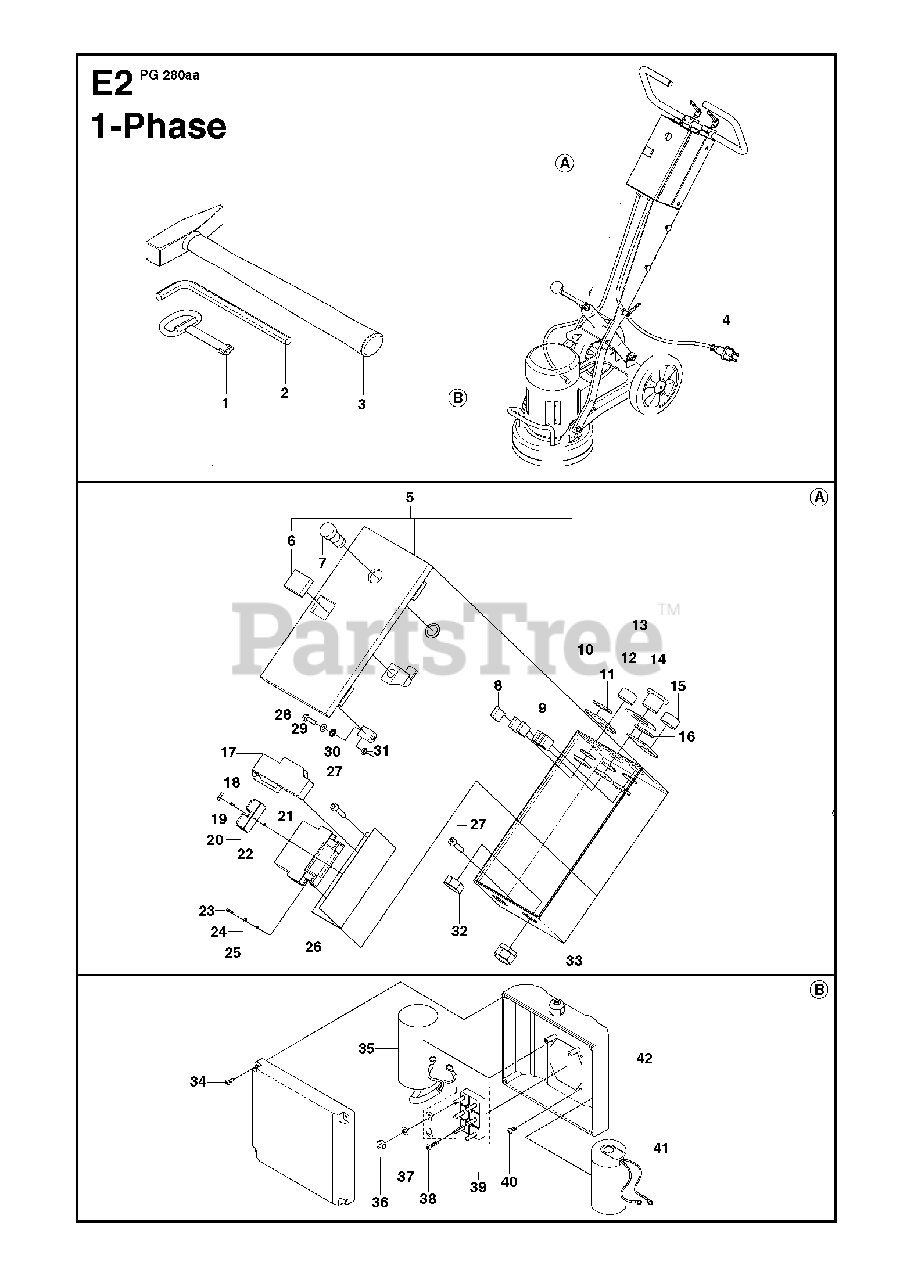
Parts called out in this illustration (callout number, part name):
4	CABLEIncl plug, 220V, US
4	CABLEIncl plug, 110V, US
5	ELECTRIC BOXEU/AUS/US/JP, 230V
7	LEDEU/AUS/CH/US, 220V
17	PROTECTION220V, EU/AUS/US
17	PROTECTION110V, US/UK/JP
21	HEXAGON LOCKING NUT
22	CONTACTOR220V, EU/AUS/US
22	CONTACTOR110V, US/UK/JP
25	HEXAGON LOCKING NUT
28	SCREW EHHM
32	NUTEU/AUS/US/JP, 230V
33	CABLE GROMMETEU/AUS/US/JP, 230V
35	CAPACITOR100-120V, 60Hz, US/JP
35	CAPACITOR200-230V, US/CAN/Brazil
35	CAPACITOR100-120V, 50Hz, UK/JP
41	CAPACITOR100-120V, 60Hz, US/JP
41	CAPACITOR200-230V, EU/US/CAN/Brazil
41	CAPACITOR110V, 50Hz, UK/JP
